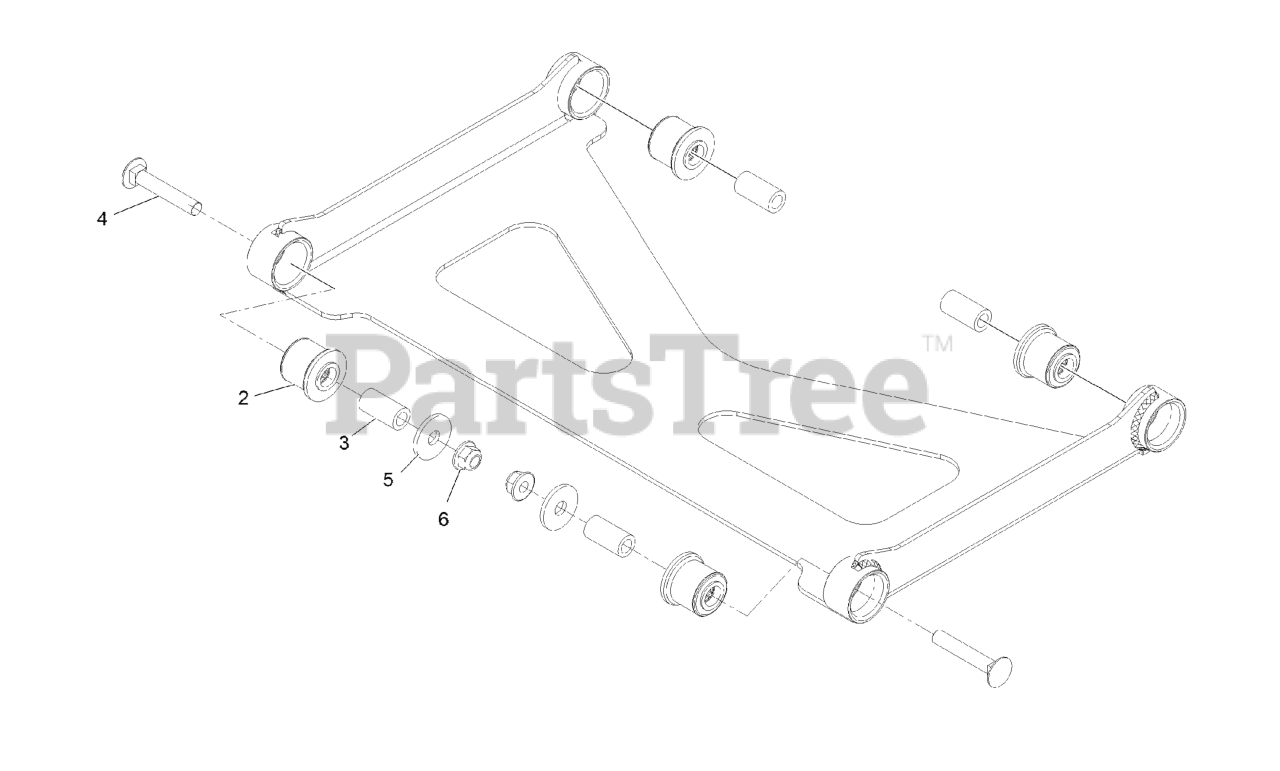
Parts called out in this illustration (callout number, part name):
2	BUSHING-RUBBER, SUSPENSION
4	Bolt-Carriage 3/8-16 X 2 1/4
5	WASHER
6	NUT-HF, NI
